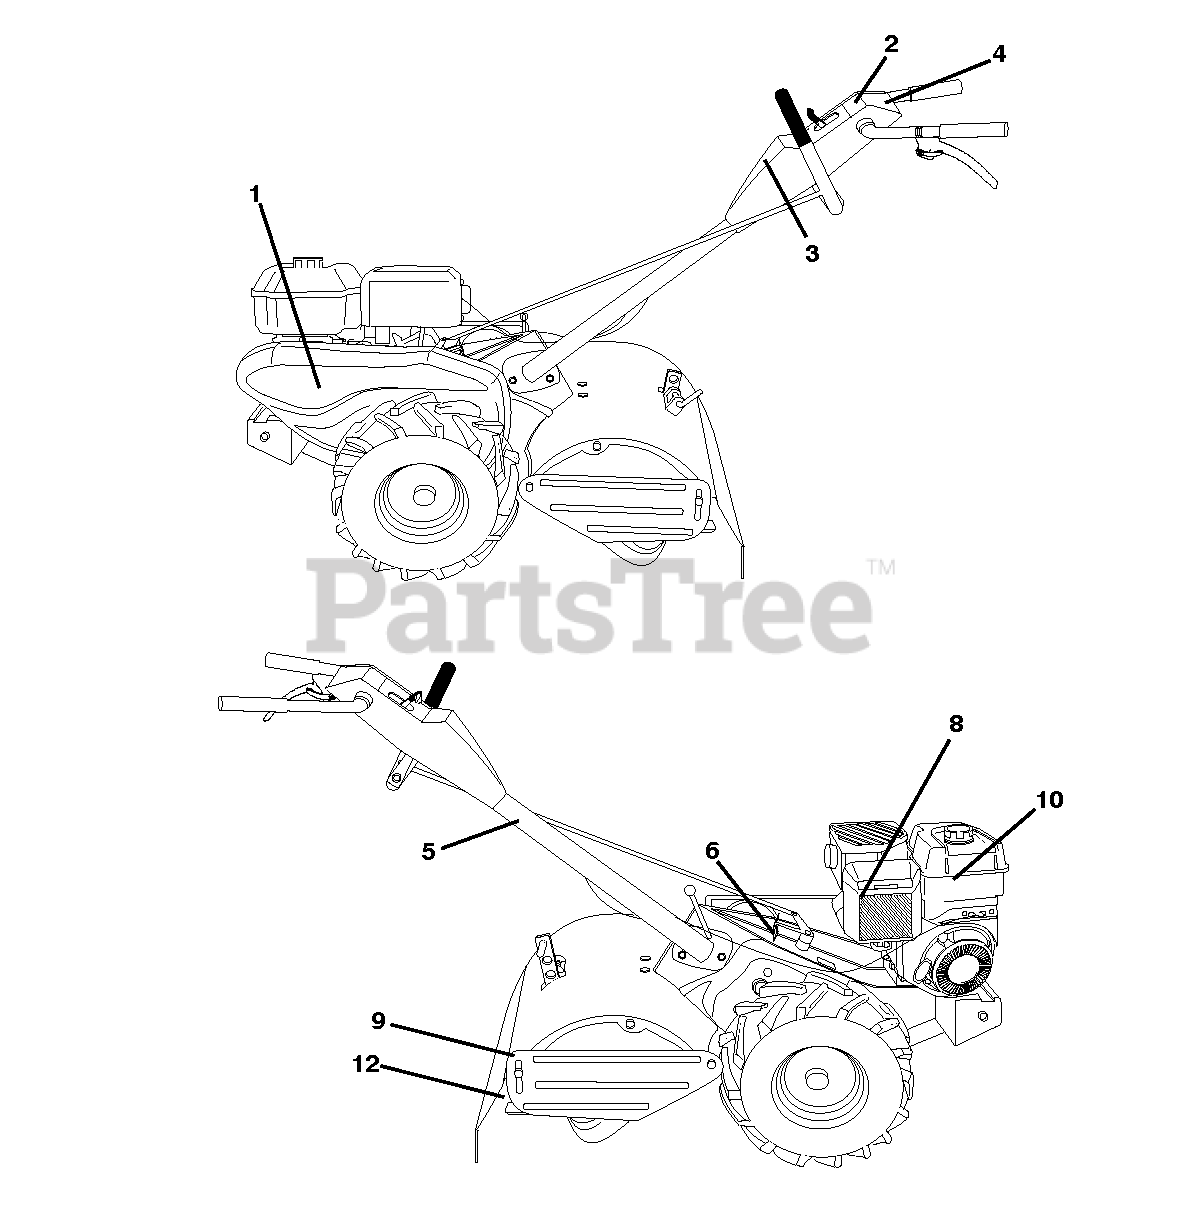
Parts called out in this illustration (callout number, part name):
6	DECAL.SHIFT.INDICATOR.TILLER
9	DECAL EUROPE STANDARD CE
10	DECAL.B&S.900.TANK.REF.276991
